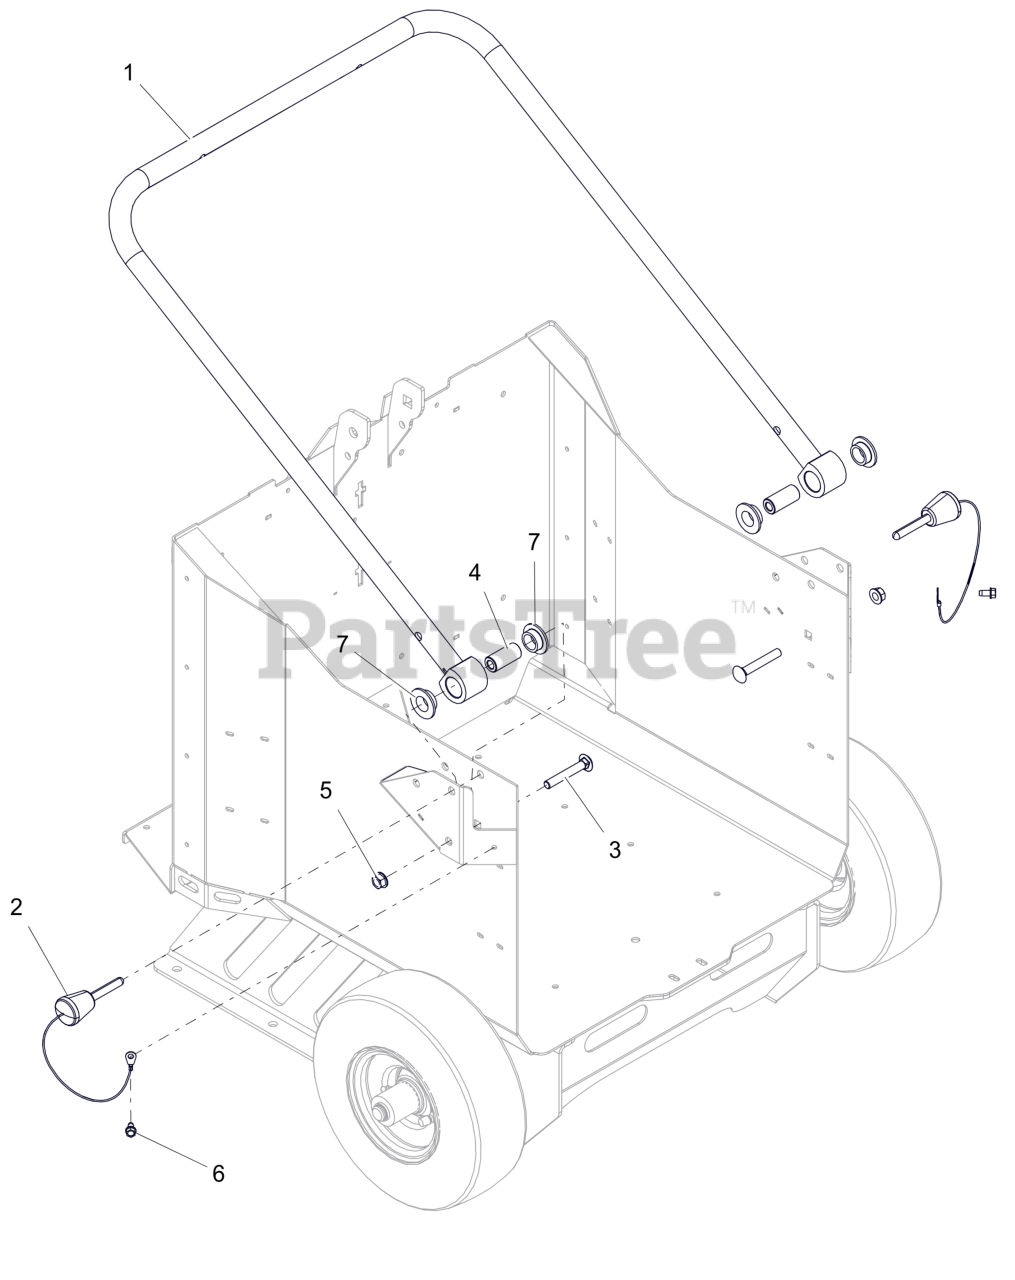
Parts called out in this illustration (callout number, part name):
1	WLDMT, HANDLE (BLUE)
2	PIN, MAGNETIC .375X2.188
3	BLT,RHSN .38-16X2.50 G5 ZCC
4	SPACER, STEERING ARM
5	NUT-LK-CTR-FLG .375-16 GF ZCC
6	SCR-TAP .25-20X.50 HWH ZCC
7	BSHG-FLG .762X1.48X.44 NYL
